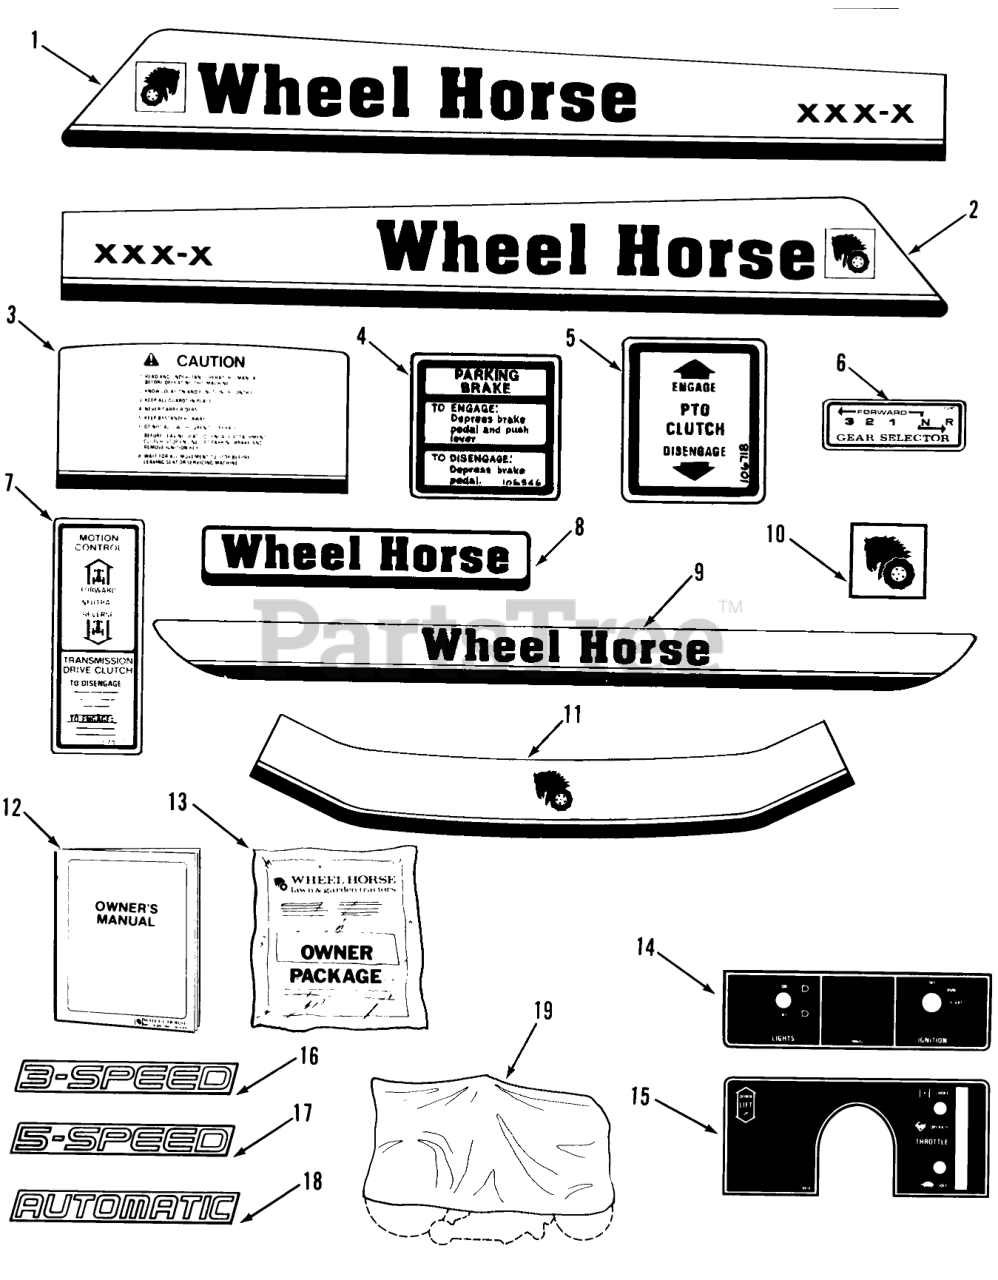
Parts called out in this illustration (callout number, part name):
1	DECAL HOOD RH
2	DECAL HOOD LH
3	DECAL CAUTION
4	Decal Parking Brake
5	DECAL-PTO CLUTCH
6	DECAL-SHIFT
7	Decal-Speed Control 211-A
8	DECAL REAR FENDER
9	Decal-Rear Fender
10	DECAL HOOD FRONT
11	Decal-Hood Front
12	Owners Manual-Tractor
13	New Tractor Loose Parts Package 208-3 Only
14	DECAL-BACK PLATE-SWI
15	DECAL - LOWER DASH
16	DECAL 3SPD
17	DECAL 5SPD
18	DECAL AUTOMATIC
19	Vinyl Tractor Cover
